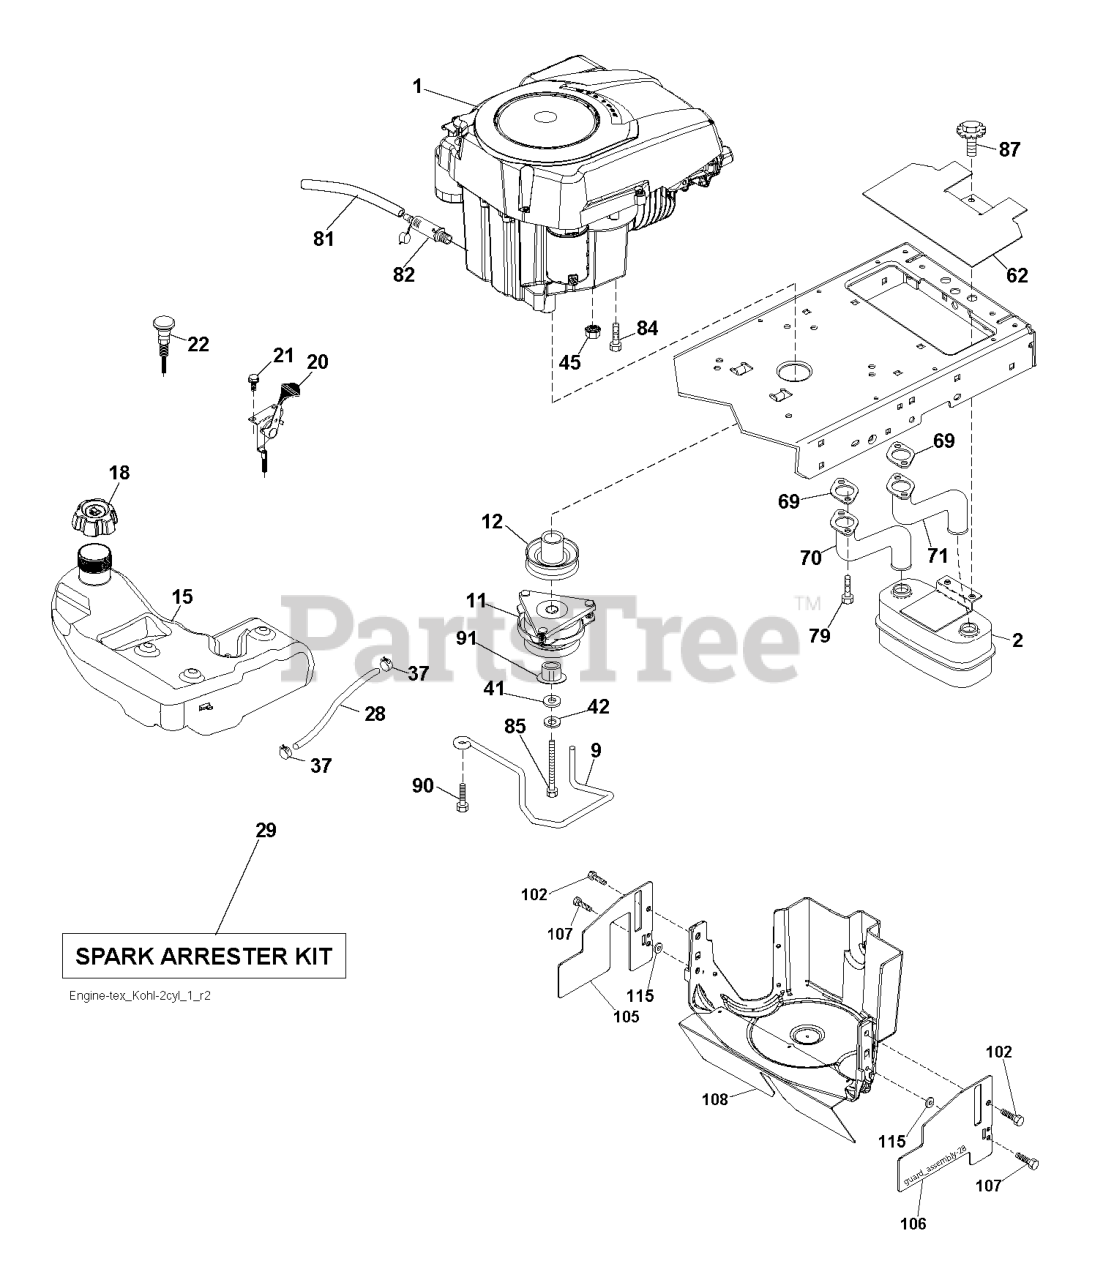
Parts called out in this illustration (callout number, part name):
2	MUFFLER.TWIN.CYL.LOW.TONE
9	KEEPER.BELT.ENGINE.4.2
11	CLUTCH.ELECTRIC.LT.48"*
12	PULLEY.ENGINE.TUFFTORQ
15	TANK.FUEL.4GAL
18	CAP.FUEL.TANK.3"GREY
20	THROTTLE CONTROL
21	SCREW.#10 X 0.750.BOS
22	CONTROL.CHOKE.ERGO.PUSH-IN.BLA
28	REPL BY 532 00 85-43
29	KIT.SPARK ARRESTOR 794945 B&S
37	HOSE CLAMP
42	LOCKWASHER
45	NUT
62	RP SHIELD HEAT MUFFLER
70	RP.PIPE-EXHAUST LH
71	RP.PIPE-EXHAUST RH
79	SCREW.SOCKET HD.5/16-1
81	TUBE, DRAIN OIL ASM.
82	PLUG DRAIN OIL EASY
84	SCREW 3/8-16X1
85	BOLT HEX 7/16-20X4-1/4"
87	BOLT.5/16-18UNCX3/4 W/SEMS.BLK
90	SCREW 3/8-16X1
91	BUSHING.1.375OD
105	SHIELD.SIDE.RH.3842"TEX FRENCH
106	SHIELD.SIDE.RH.46"FRENCH.TEX
107	SCREW.1/4-20X5/8
108	COVER
115	PALNUT 1/4
118	SCREW, 5/16-18 X 1/2
